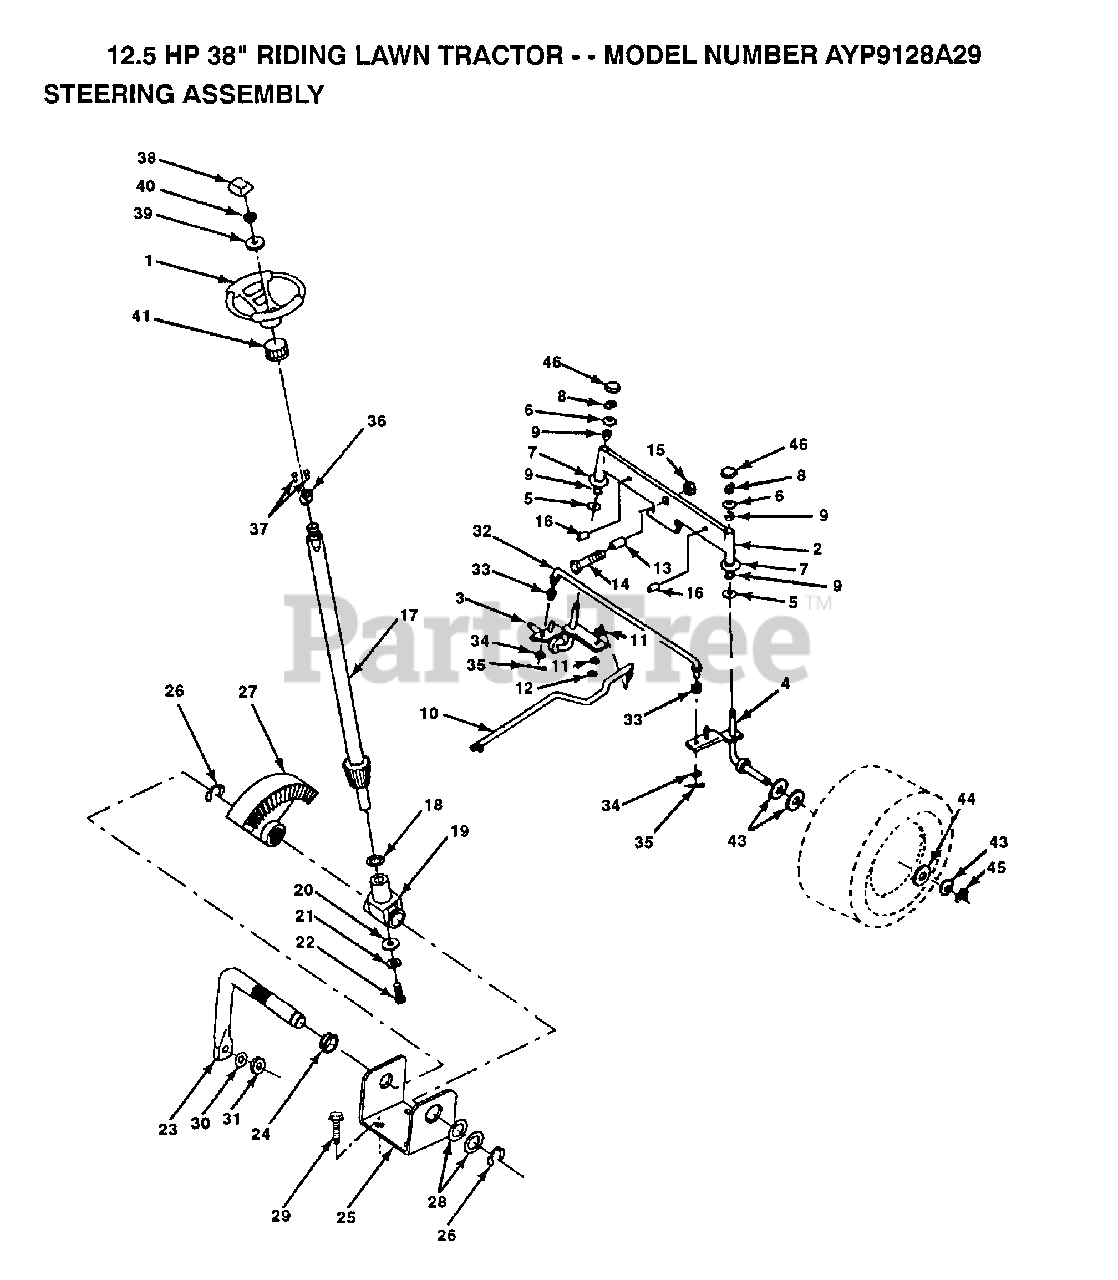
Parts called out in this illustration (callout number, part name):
4	SPINDLE ASM RH
5	WASHER .T
6	WASHER
7	WASHER
8	RING
9	COL. SRTG. BEAR.
11	LOCKWASHER
13	BEARING
14	BOLT HEX 5/8-11
16	AXLE PIN
17	STEERING SHAFT
18	THRUST WASHER
19	SUPPORT.SHAFT
21	LOCKWASHER
22	"SCREW,SPECIAL"
24	NYLINER T
25	"BRKT,STEERING"
26	RING
28	WASHER .T
29	SCREW
30	LOCKWASHER
32	TIE ROD
34	WASHER
35	COTTER PIN
38	INSERT-WHEEL LT
39	WASHER
41	ADAPTER LT
43	WASHER
44	WASHER
45	RING
46	CAP
